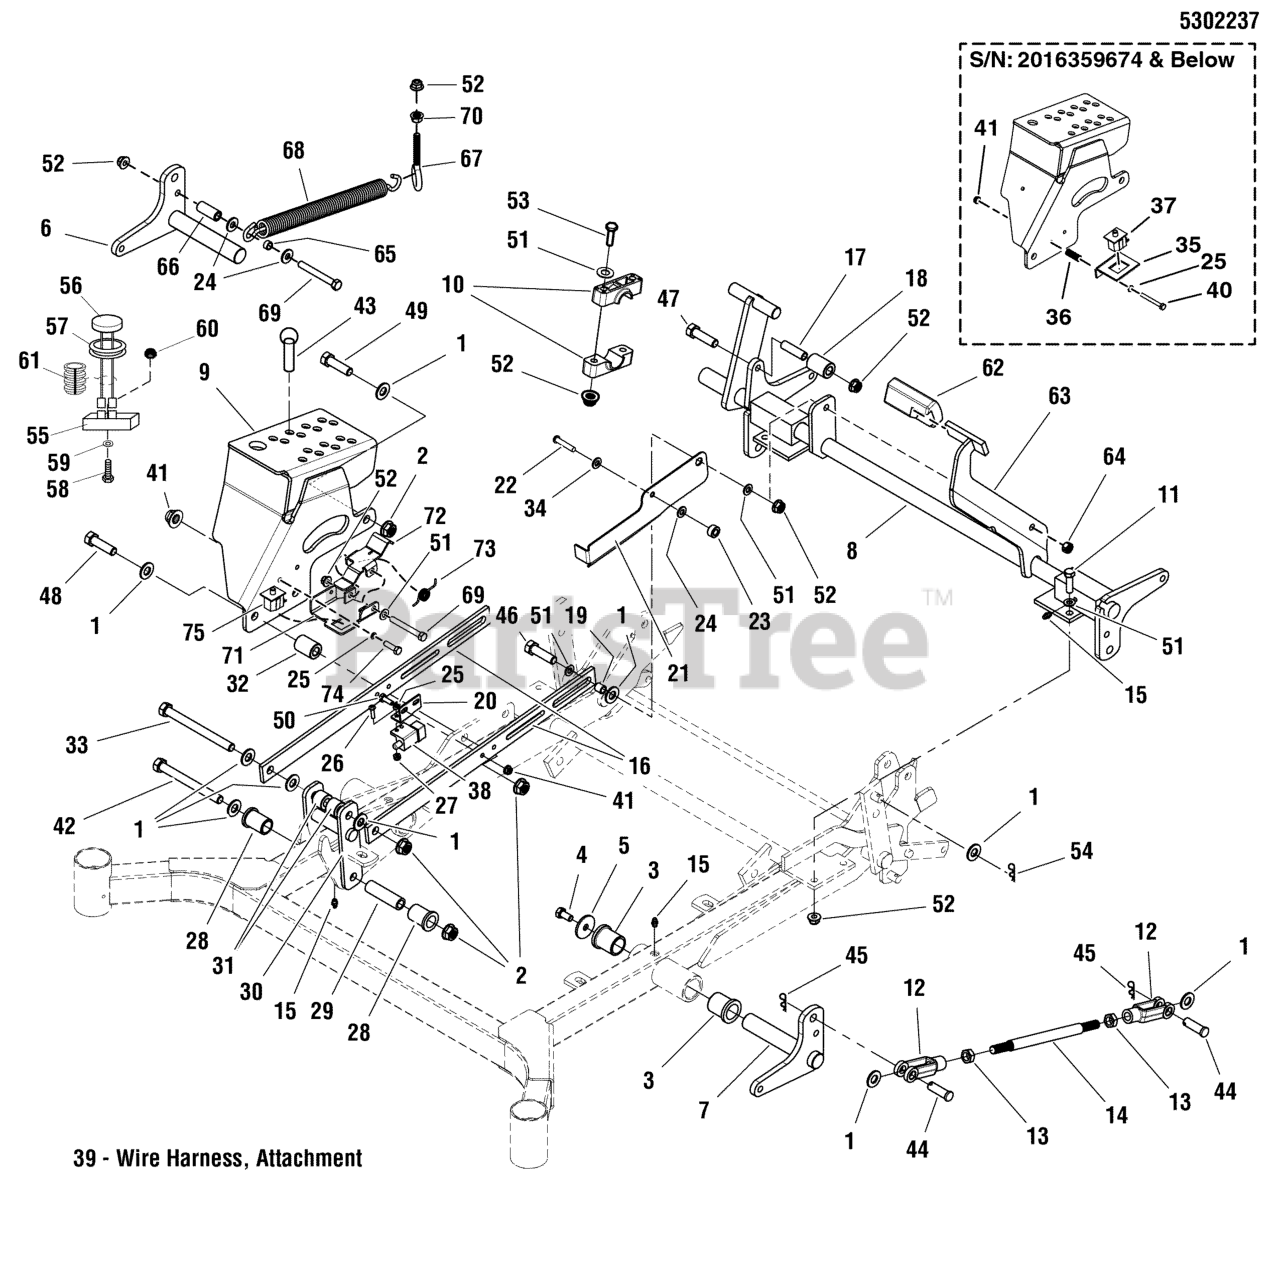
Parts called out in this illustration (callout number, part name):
1	WASHER, 1/2 SAE
2	NUT, Hex Flange, Nylock, 1/2-13
3	BUSHING, FLANGE
4	BOLT, 3/8-16 X 3/4, PLT W/PATCH
5	WASHER, .390 X 1.50 X .109, YZ
6	WELD., DECK LIFT LEVER - RH - RED
7	WELD., DECK LIFT LEVER - LH - RED
8	WELD, DECK LIFT SHAFT - OUTFRONT - RED
9	WELD, CUT HEIGHT BOX - RED
10	PIVOT BLOCK, PLASTIC
11	BOLT, 3/8-16 X 1-1/4" GD5 CZ
12	CLEVIS, 1/2-20, STEEL
13	NUT, 1/2-20 HEX JAM
14	ROD, DECK LIFT, OUTFRONT
15	GREASE FITTING, 1/4-28 STRAIGHT
16	BAR, ACTUATOR LINK - RED
17	SPACER, .38 X .50 X 1.78 YZ
18	SPACER, .51 X 1.00 X 1.47 YZ
19	SPACER, .38 X .50 X .50, YZ
20	PLATE, SWITCH MOUNT - RED
21	PLATE, SWITCH COVER - RED
22	PIN-CLEVIS, 5/16 X 1 YZ
23	COLLAR, 5/16 SET
24	WASHER, 5/16 USS
25	WASHER, 1/4 SAE
26	SCREW, #10-24 X 3/4 ROUND PHILLIPS
27	NUT, #10-24 HEX NYLON LOCK
28	BUSHING, FLANGED, 3/4 X 1 X 1
29	SPACER, .51 X .75 X 2.66
30	WELD, PIVOT LINK - ACTUATOR - RED
31	SPACER, .52 X 1.00 X .75
32	SPACER, .52 X 1.00 X 1.38 YZ
33	BOLT-1/2-13 X 5 GD5 YZ
34	WASHER, 5/16" SAE
35	MOUNT, LOW PROFILE SWITCH - RED
36	SPRING, .325 X .475 X 1.25, BLK E-COAT
37	SWITCH, LOW PROF, NC/NO
38	SWITCH, PLUNGER, N.O./N.C.
39	WIRE HARNESS, ATTACHMENT, DECK
40	BOLT, 1/4-20 X 2-1/4, GD5
41	NUT, 1/4-20 HEX NYLOCK FLANGE
42	BOLT, 1/2-13 X 4" GD5 CZ
43	PIN-COTTERLESS
44	CLEVIS PIN, 1/2 X 1.36 SAE STANDARD
45	PIN, 3/32 X .750, COT, ZINC/CLEAR
46	BOLT, 3/8-16 X 1-1/2" GD5 CZ
47	BOLT, 3/8-16 X 2-3/4" GD5 CZ
48	BOLT, 1/2-13 X 2-3/4 GD5 CZ
49	BOLT, 1/2-13 X 1-1/2 GD5 CZ
50	BOLT, 1/4-20 X 3/4 GD5 YZ
51	WASHER, 3/8 SAE
52	NUT, 3/8-16 HEX NYLOCK FLANGE
53	BOLT, 3/8-16 X 2-1/2" GD5 CZ
54	PIN, HAIR, .0915 X 1-7/8
55	FLASHER, 90 FPM, OUT FRONT MOWER
56	INDICATOR LAMP, RED, LED
57	GROMMET, 1/2
58	BOLT, 1/4-20 X 1-1/2, GD5
59	WASHER, 1/4 SAE
60	NUT, 1/4-20 HEX NYLOCK FLANGE
61	WIRE LOOM, 3/8 ID X 7" LONG
62	PEDAL, Rubber
63	WELD, QUICK DECK LIFT PEDAL - RED
64	NUT, 3/8-16 HEX SIDE LOCK
65	SPACER, .38 X .50 X .27
66	SPACER, .39 X .63 X 1.50
67	EYEBOLT, 3/8-16 X 4, 2.13THRD, .75EYE, C
68	SPRING, DECK LIFT ASSIST
69	BOLT, 3/8-16 X 3" GD5 CZ
70	NUT, 3/8-16 HEX SERRATED FLANGE
71	WELD, SWITCH MOUNT - BLACK
72	INDICATOR, DECK POSITION - BLK
73	SPRING, TORSION, .591ID X .40LG X .095WR
74	BOLT, 1/4-20 X 1" GD5 CZ
75	SWITCH, LOWER PRO, NC/NC
